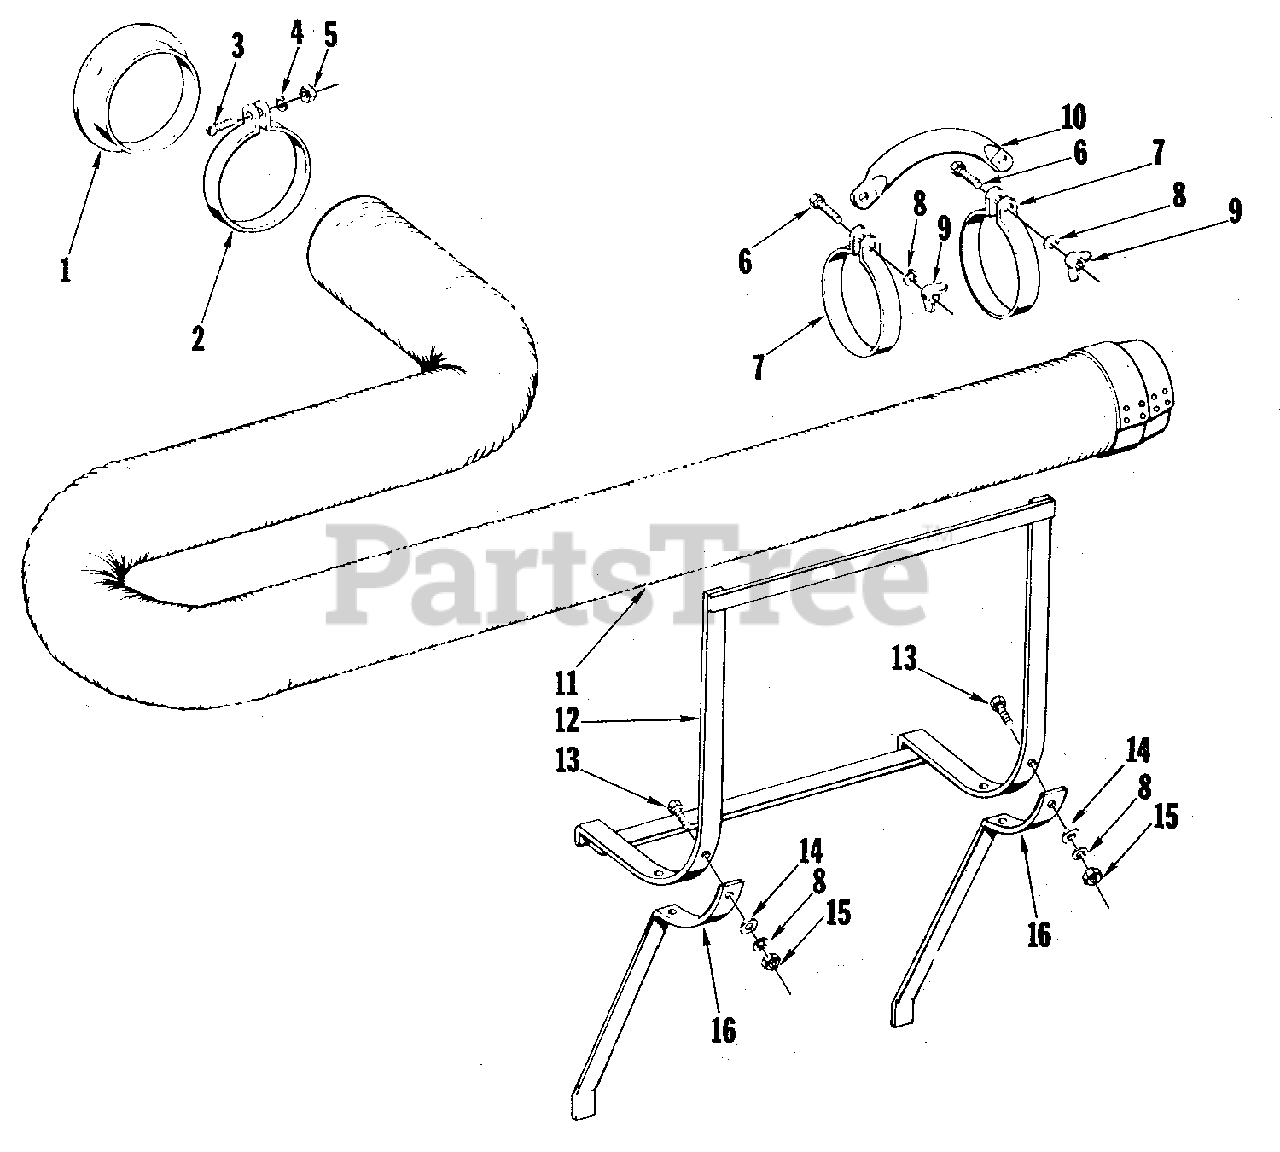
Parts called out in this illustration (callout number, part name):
1	FLANGE, Hose
3	SCREW, Machine, 1/4-20 x 3
4	WASHER, Lock, 1/4
5	NUT, Hex, 1/4-20
6	SCREW, Cap, 5/16-18 x 3/4
8	WASHER, Lock, 5/16"
9	NUT, Wing, 5/16-18
10	HANDLE, Hose
11	HOSE ASSEMBLY
12	CARRIER ASSEMBLY, Hose
13	SCREW, Cap, 5/16-18 x 7/8
14	WASHER, Flat, 5/16
15	NUT, Hex, 5/16-18
16	SUPPORT, Carrier
